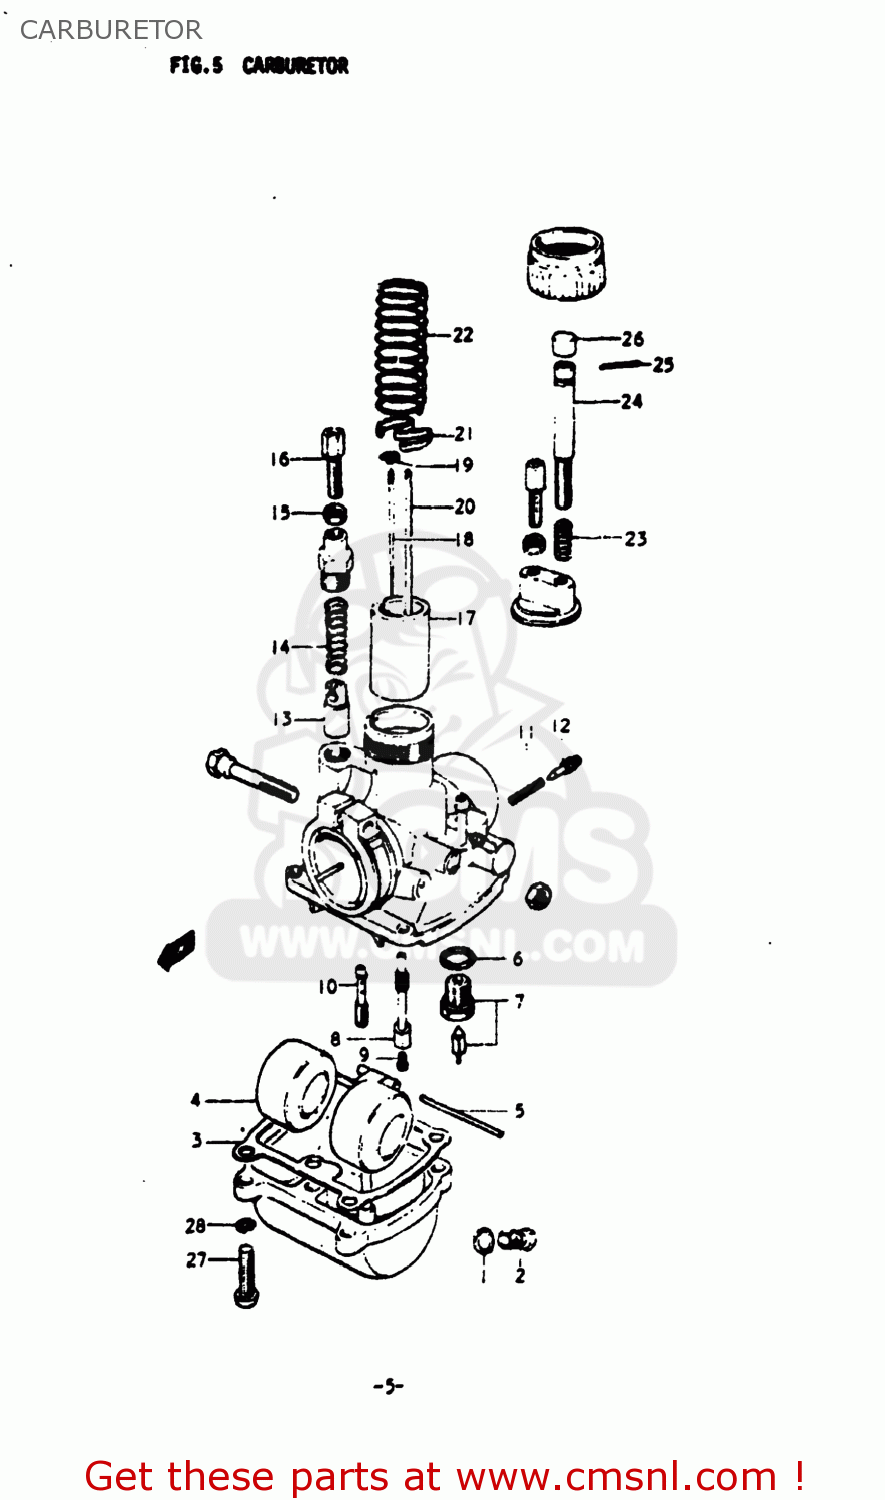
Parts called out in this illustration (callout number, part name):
0	CARBURETOR ASSEMBLY
1	GASKET,DRAIN,PLUG (NAS)
2	PLUG
3	GASKET,FLOAT CHAMBER (NAS)
4	FLOAT
5	PIN,FLOAT
6	GASKET,NEEDLE VALVE (NAS)
7	VALVE ASSEMBLY,NEEDLE
8	JET,NEEDLE
9	JET
10	JET
11	SPRING
12	SCREW,PILOT AIR
13	PLUNGER,STARTER
14	SPRING
15	NUT
16	ADJUSTER,CABLE
17	VALVE,THROTTLE
18	NEEDLE,JET
19	CLIP,NEEDLE
20	ROD,THROTTLE VALVE STOP
21	PLATE,THROTTLE VALVE
22	SPRING,THROTTLE VALVE
23	SPRING,THROTTLE STOP SCREW
24	SCREW,THROTTLE STOP
25	PIN 12X10
26	CAP,THROTTLE VALVE STOP SCREW
27	SCREW
28	LOCK WASHER
